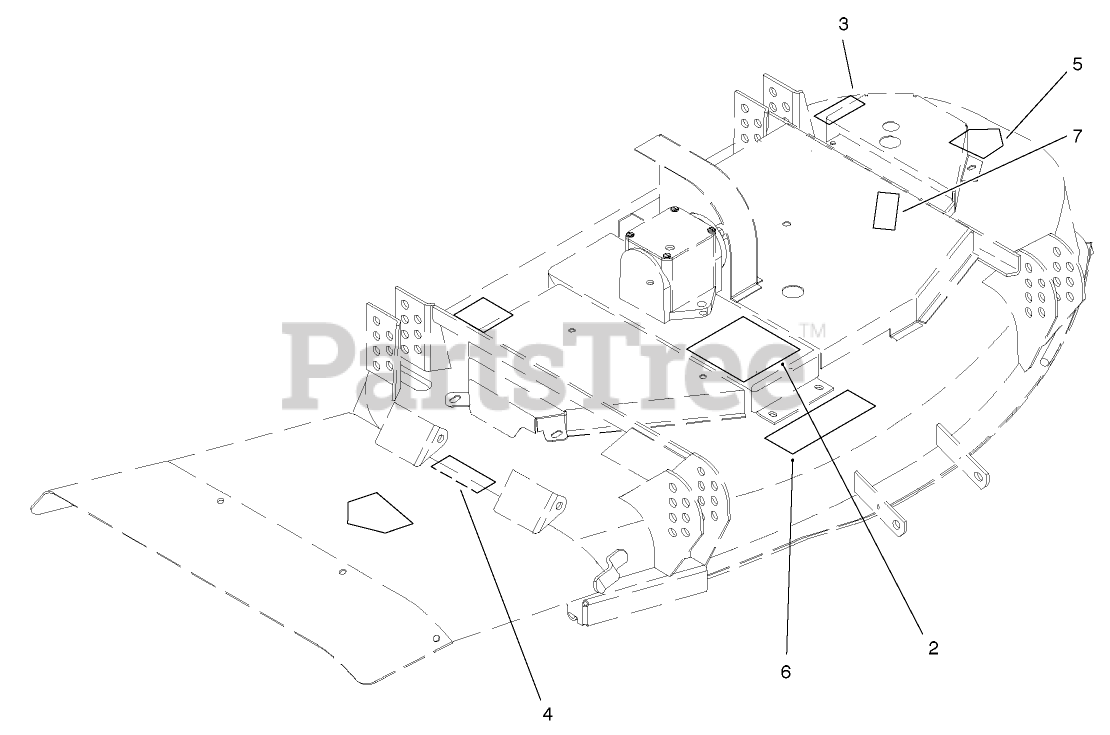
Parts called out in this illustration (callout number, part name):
2	DECAL-44 INCH
3	DECAL-TORQUE, BLADE BOLT
4	DECAL-WARNING, DEFLECTOR
5	DECAL-DANGER
6	DECAL-DANGER
